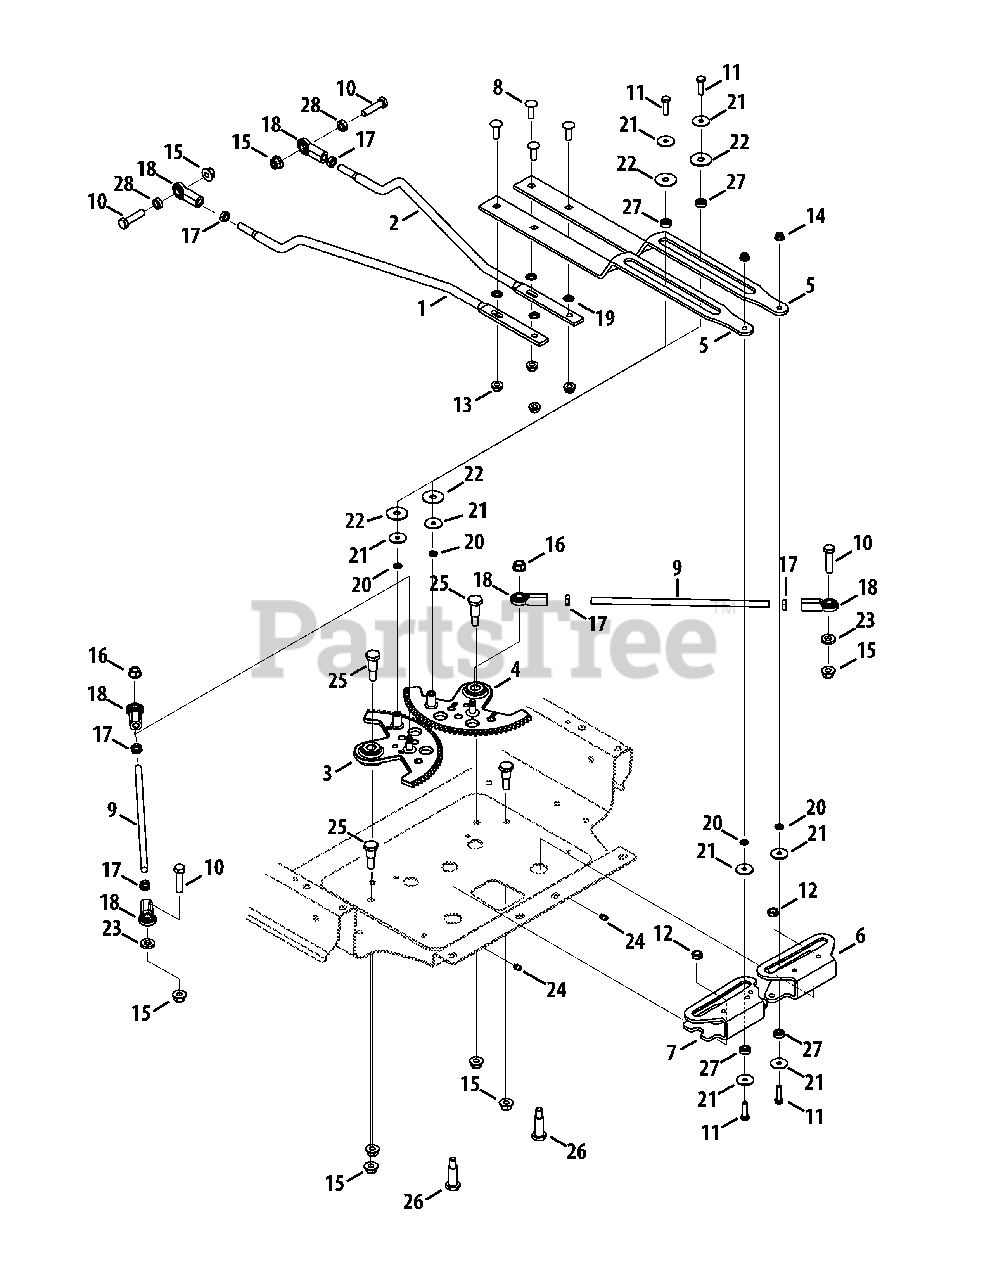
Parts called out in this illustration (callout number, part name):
1	Hydro Link, RH
2	Hydro Link, LH
3	Steering Gear Assembly, RH
4	Steering Gear Assembly, LH
5	Control Link
6	Speed Cam Plate, LH
7	Speed Cam Plate, RH
8	Carriage Screw, 5/16-18 x 1.00
9	Drag Link, .375 Dia.
10	Hex Screw, 3/8-16 x 1.50
11	Hex Screw, 1/4-20 x 1.00
12	Nut, Jamlock, 3/8-16
13	Flange Lock Nut, 5/16-18
14	Flange Lock Nut, 1/4-20
15	Flange Lock Nut, 3/8-16
16	Nut, 5/16-18, Centerlock
17	Jam Nut, 3/8-24
18	Female Ball-Joint
19	Speed Nut, .3125 ID
20	Push Nut, .25 ID x .50 OD
21	Flat Washer, .285 x 1.25 x .060
22	Washer, .355 x 1.25 x .048
23	Flat Washer, .407 x .812 x .135
24	Grease Fitting, 3/16
25	Shoulder Screw, 3/8-16 x .625 x .875
26	Shoulder Screw, .500 x 1.25 x 3/8-16
27	Ball Bearing, .25 x .625
28	Spacer, .380 ID x .625 OD x .21
